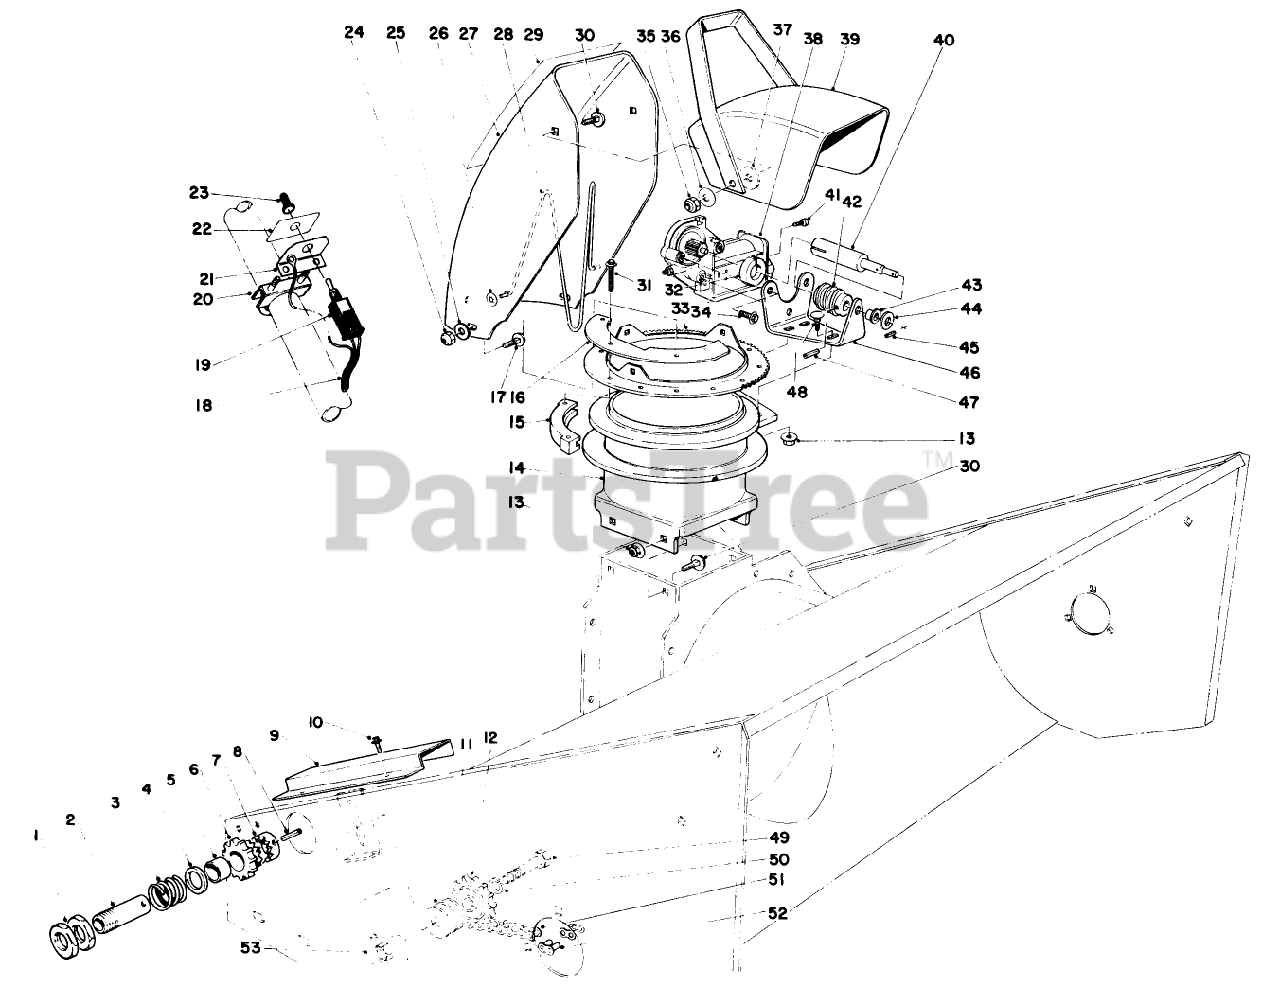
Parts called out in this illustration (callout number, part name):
1	THIN NUT
2	CLUTCH SLEEVE
3	COMP. SPRING
6	CLUTCH SPROCKET
7	CLUTCH COLLAR
8	PIN-ROLL
9	Chain Cover
10	SCREW-HWHTF
11	WASHER-FLAT
12	IDLER SPRKT (60016)
13	NUT-HHF, WHIZ
14	Chute Transition
15	RETAINER-CHUTE
16	Stop-Chute Rotator
17	SCREW-CARR
18	WIRE HARNESS
19	Toggle Switch (Incl. Ref.#23)
20	CLAMP
21	Toggle Switch Mount
22	DECAL
23	BOOT-SWITCH
24	NUT-LOCK, NI
25	WASHER-PLAIN
26	NUT-PUSH
27	Upper Chute
28	WIRE-CHUTE
29	Decal-Warning
30	SCREW-CARR
31	SCREW-SPECIAL
32	SPLIT COLLAR
33	RING - CHUTE SWIVEL
34	SCREW-HHF
35	NUT-LOCK, CONE
36	WASHER-BELLEVILLE
37	WASHER-RUBBER
38	ELEC GEAR MOTOR
39	Deflector
40	WORM GEAR SHAFT
41	SCREW-HSH
42	GEAR-WORM, CHUTE
43	FLANGE BSHG #FF-310-3
44	WASHER-FLAT
45	3/32 X 9/16 ROLL PIN
46	Motor Mount
47	PIN-SPRING
48	BOLT-CARR
49	SCREW-HH
50	WASHER-LOCK
51	ROLLER CHAIN (60023)
52	LINK-CHAIN
53	NUT PLATE WA (60095)
